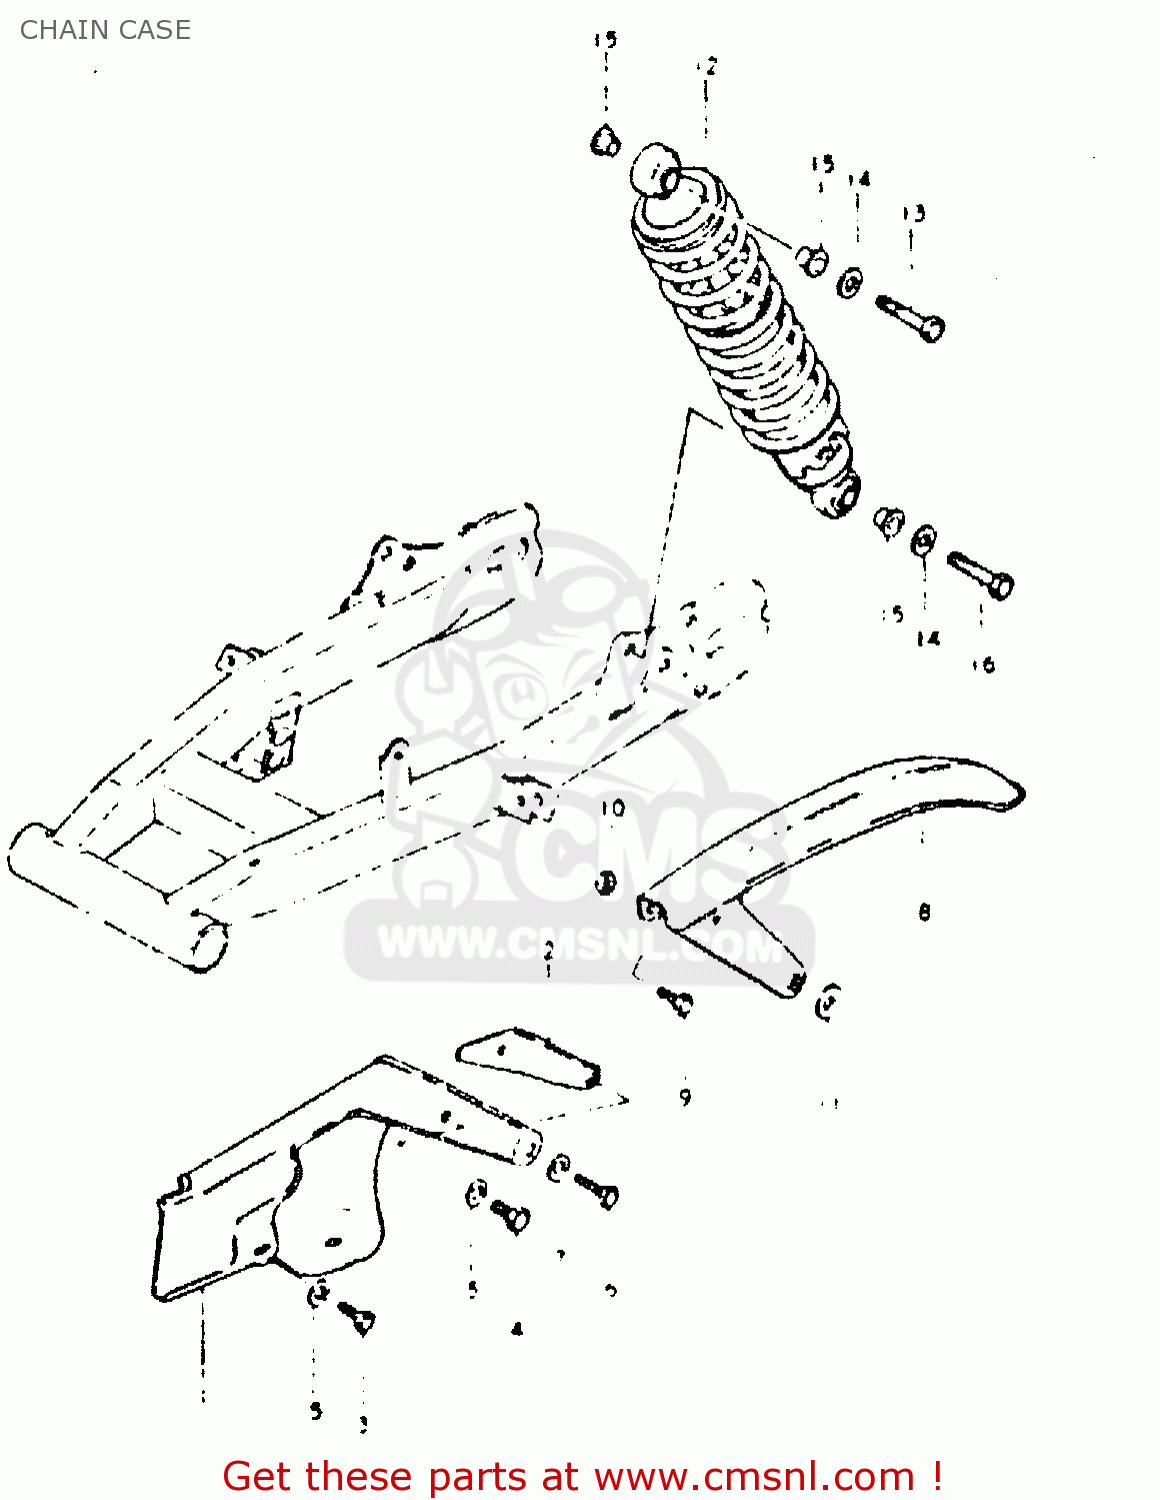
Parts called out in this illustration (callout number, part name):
1	CASE,CHAIN
2	REINFORCEMENT,CHAIN CASE
3	BOLT
4	BOLT(6X8)
5	WASHER
6	BOLT
7	WASHER
12	SHOCK ABSORBER, REAR
13	BOLT
14	WASHER
15	SPACER,RR SHK ABS INNER
16	BOLT
